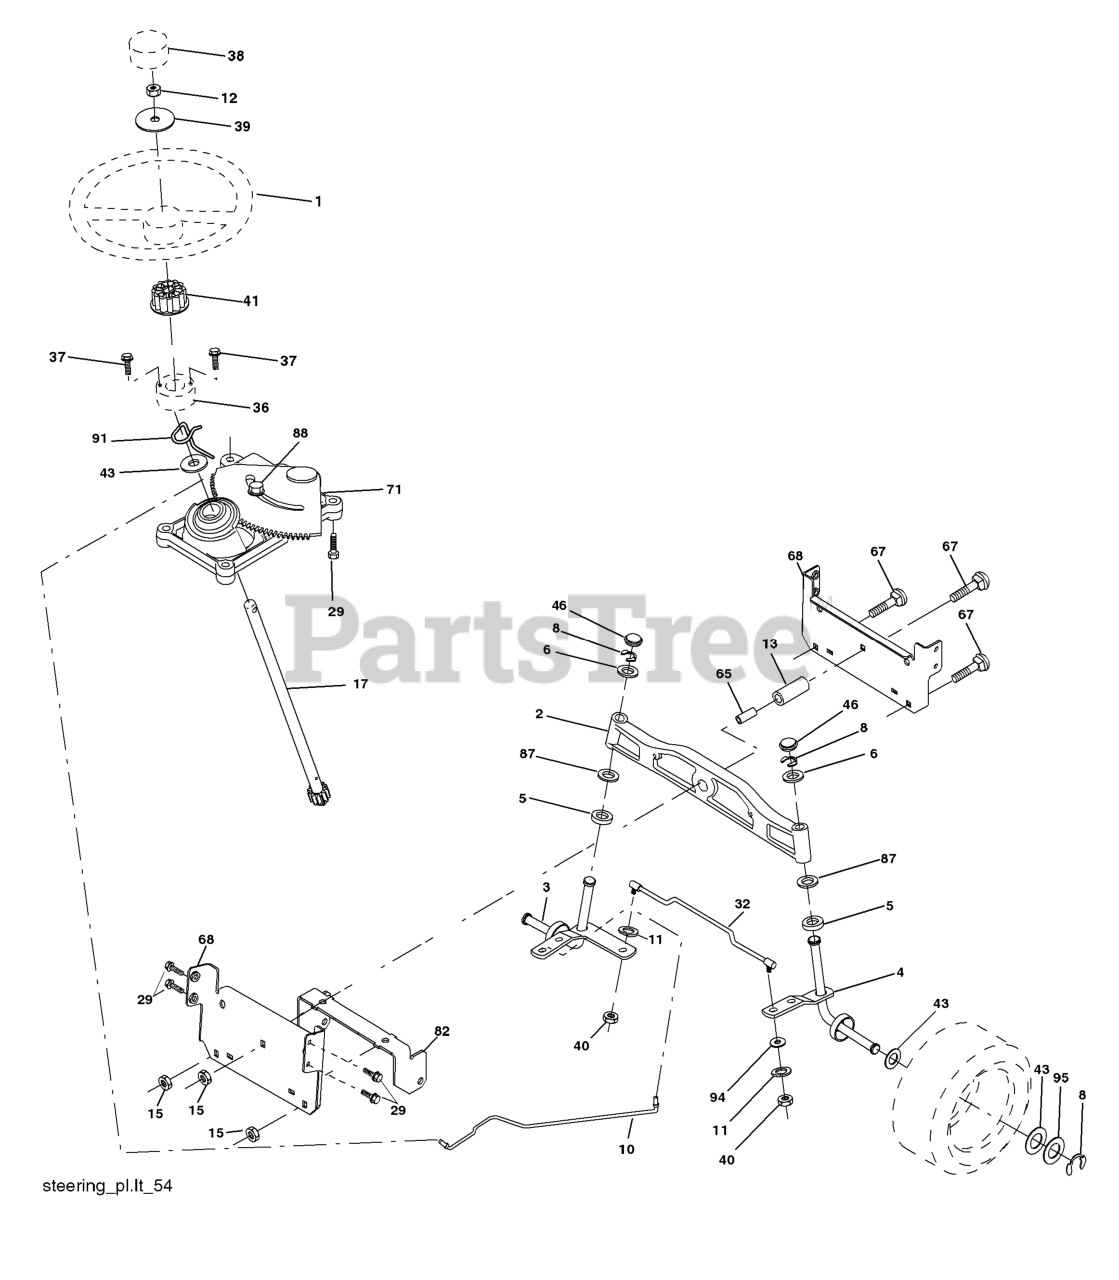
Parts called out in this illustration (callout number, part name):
1	STEERING WHEEL
2	AXLE ASSY FRONT
3	SPINDLE.ASM.LH.15"TIRES
4	SPINDLE.ASM.RH.15"TIRES
5	THRUST WASHER
10	DRAGLINK.15".TIRES.2001
11	WASHER, LOCK 3/8
12	NUT.HEX.1/2-20
13	TUBE, PIVOT AXLE
15	NUT
17	SHAFT ASM STRG
29	SCREW, 3/8-16X3/4
32	ROD TIE BALL J WSL
34	WASHER.LOCK.HVY.HLCL.SPR.5/16
36	BUSHING, STRG. BLK
37	SCREW.TT.#10-32X.5.3/8.FLANGE
38	CAP.WHEEL.STEERING.GREY
39	WASHER 9/16"ID, 2 3/8"OD
40	NUT CROWNLOCK 3/8-24
41	STEERING WHEEL ADAPTOR
46	CAP.SPINDLE.BLACK
65	SPACER BRACE AXLE
67	BOLT CARRIAGE
68	BRACE.AXLE.15"TIRES
71	STEERING ASM
82	BRACKET
87	WASHER, FLAT .781 X 1 1/2"
88	BOLT, SHOULDER 7/16-20
91	CLIP.STEERING
94	WASHER.5/16.FLAT.STE.STD.
95	WASHER.HARDENED
